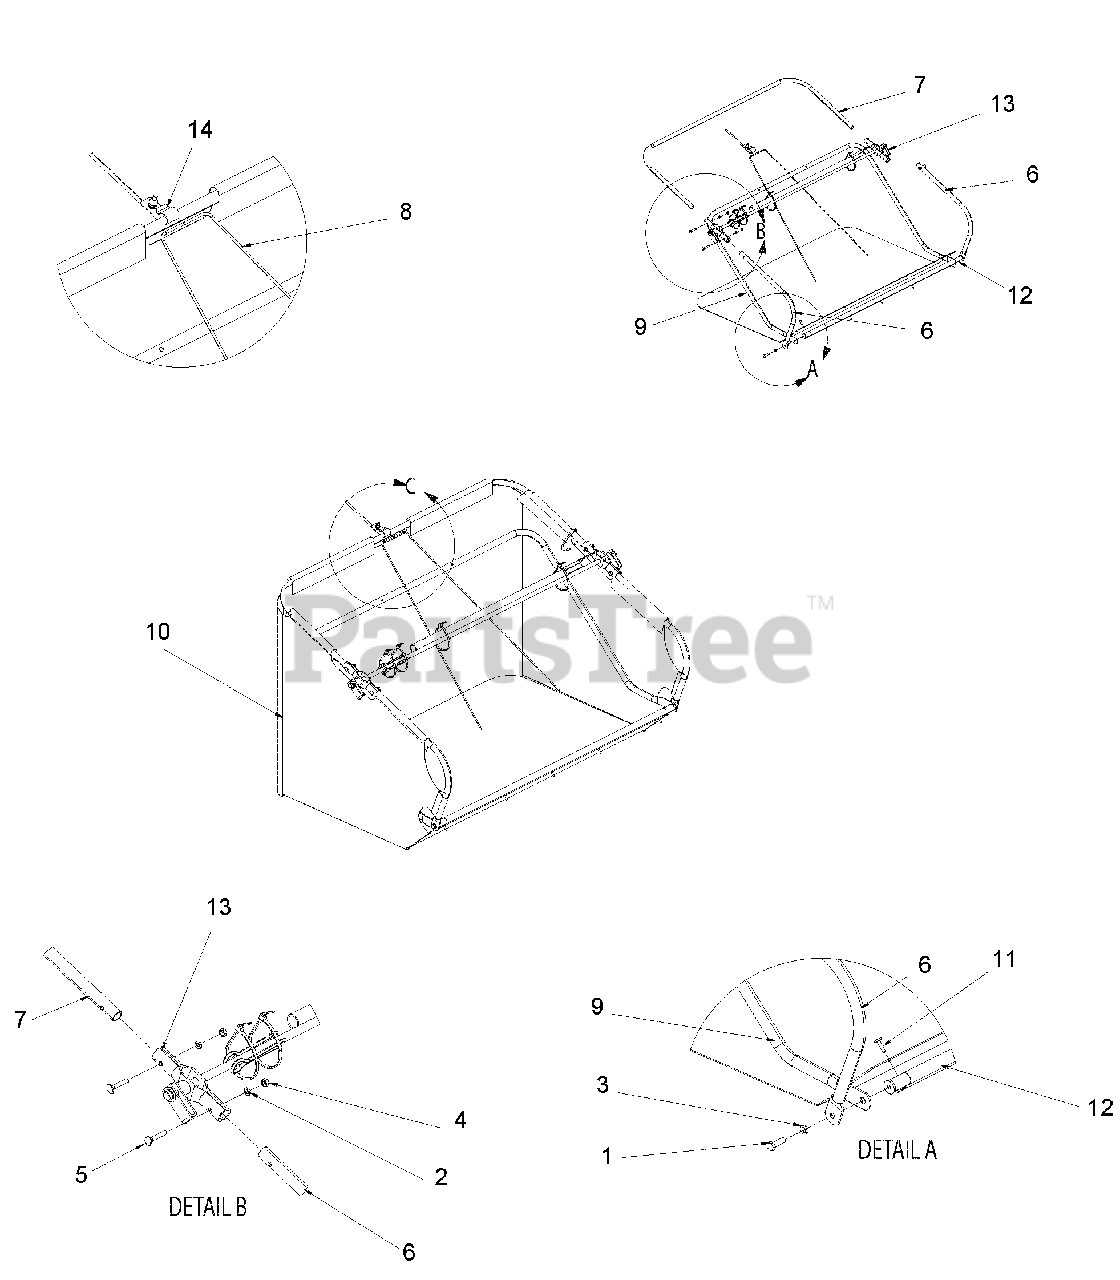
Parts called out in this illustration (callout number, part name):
1	Bolt .31-18 x 1.00 Hex 5
2	Washer, .250 Lock
3	Washer, .313 Lock
4	Nut, 1/4-20 Hex 5
5	Bolt, 1/4-20 x 1.50 Contour Head
6	Frame Basket, Front
7	Frame Basket, Rear
8	Spring, Basket
9	Frame Basket, Lower
10	Basket Bottom and Bag
11	Rivet, Bulb Tite
12	Basket Clamp Assembly
13	Pivot Rod Assembly
14	Rope and Clip Assembly
